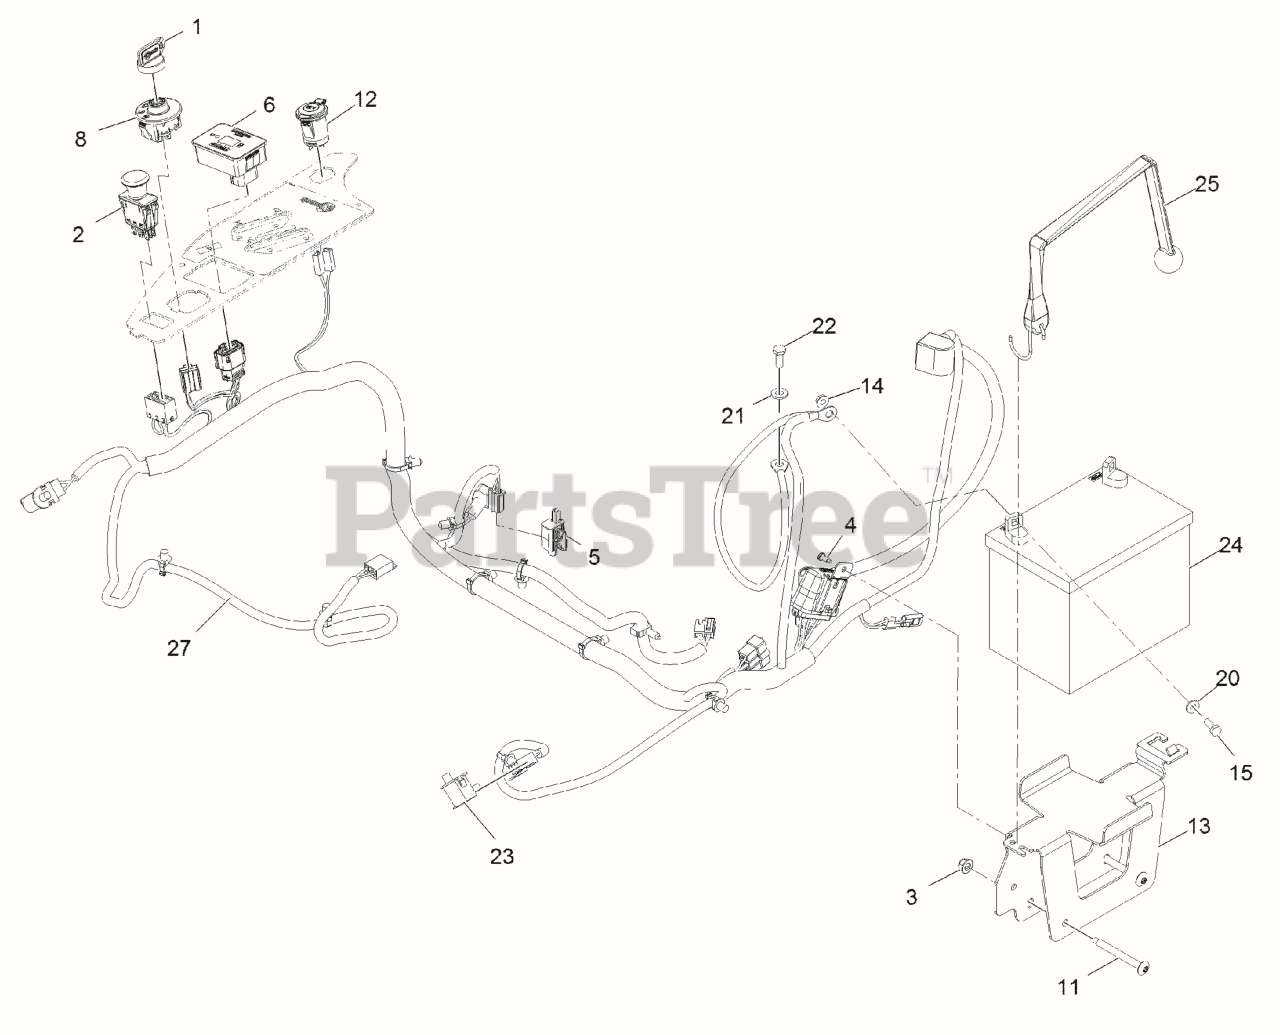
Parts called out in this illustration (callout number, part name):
1	KEYS-IGNITION (SPARE PAIR
1	KEY-IGNITION
2	SWITCH-PTO
3	NUT-HF, NI
4	SCREW-FORMING, THREAD
6	MODULE ASM
10	HARNESS-WIRE
11	SCREW-TORX
12	PORT-POWER, 12V
13	TRAY-BATTERY
15	SCREW-HH
16	SCREW-TORX
20	WASHER-FLAT
21	WASHER-PLAIN
22	SCREW-HH
23	SWITCH-BAIL
24	Battery (300 Cca, Wet)
25	STRAP-BUNGEE
27	HARNESS-WIRE
28	Mounting Bracket
